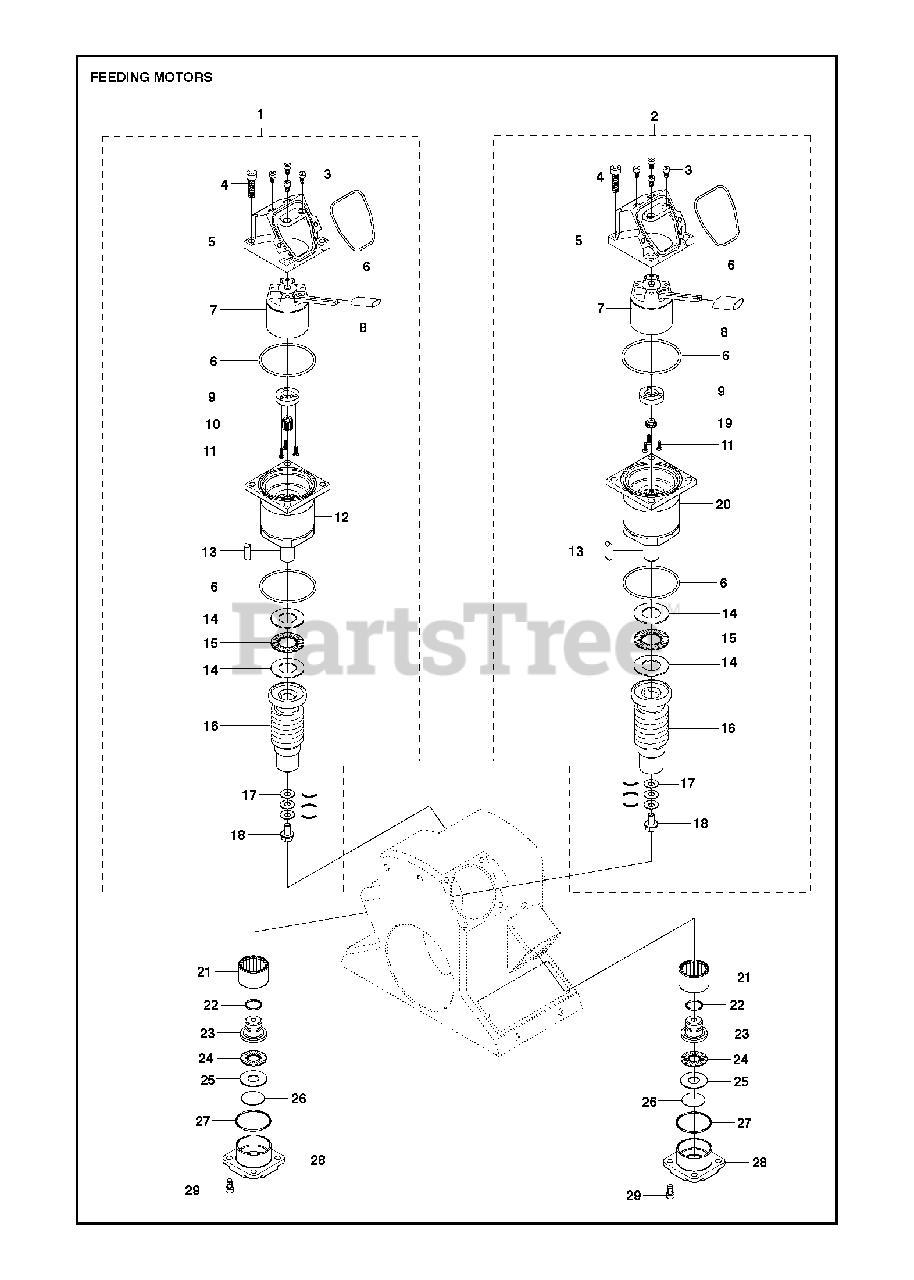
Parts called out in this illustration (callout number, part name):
1	MOTOR ASSYIncl. 3 - 18
2	MOTOR ASSYIncl. 3-9,11,13-18, 19-20
16	AUTOMATIC FEEDING SYSTEM
